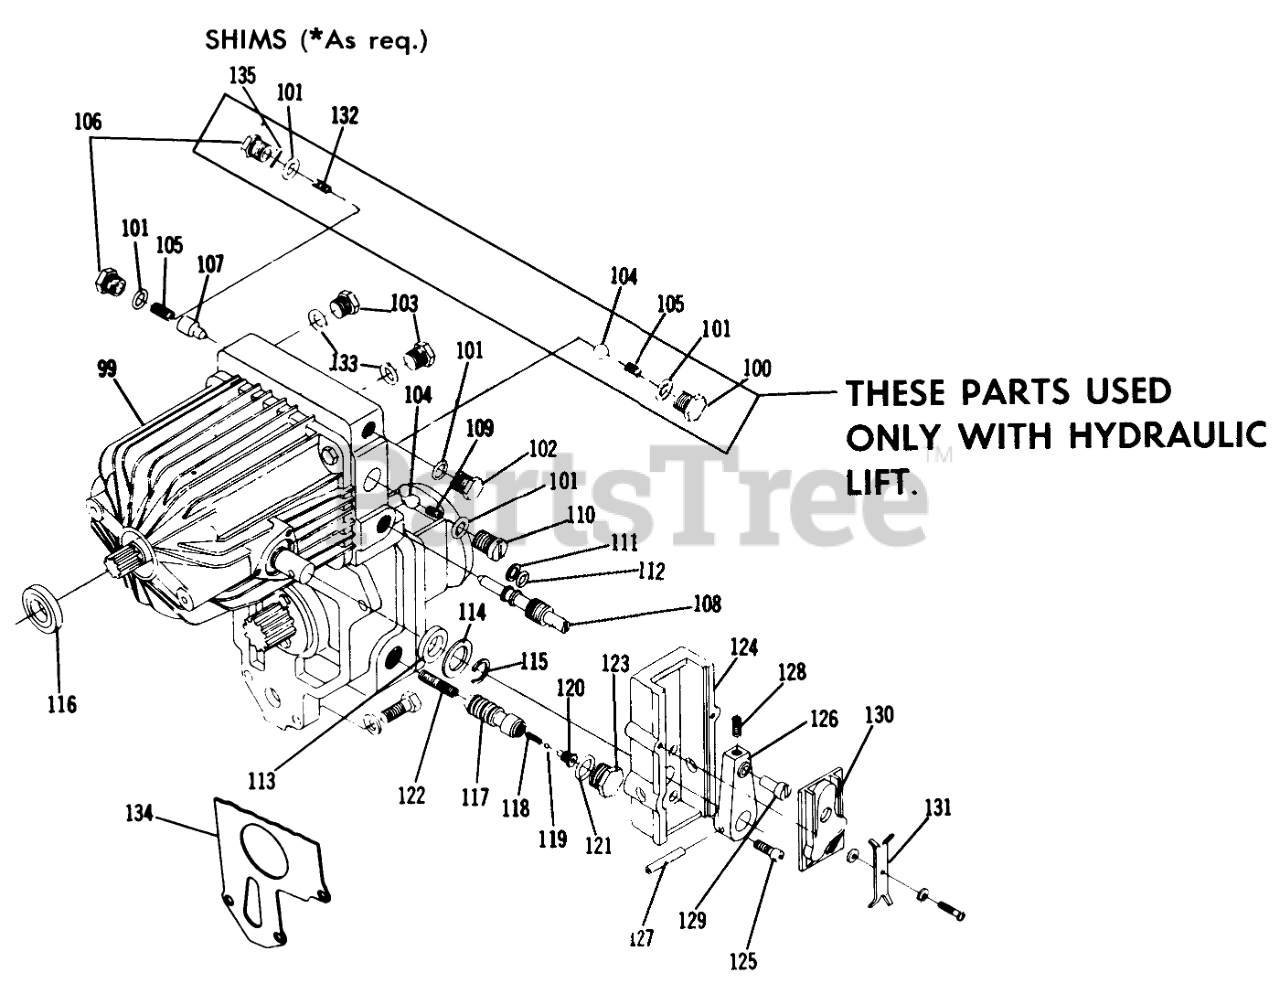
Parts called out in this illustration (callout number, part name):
99	Hydro Unit
100	Plug
101	O RING
103	Plug-Hex 9/16-18
105	Spring Chg. Rel. Valve
107	Cone
108	VALVE
109	Spring
110	PLUG
111	O-RING
112	Back Up Ring
113	SEAL
114	WASHER-LAMBERT
115	RING-LAMBERT
116	SEAL
117	Sleeve
118	SPRING
120	Valve
121	O-Ring
122	Spring
124	SUPPORT CAM BLOCK
125	SHCS 1/4-20 X 1/2
126	Belt Guide
127	PIN-ROLL 1/4 X 1 1/4
129	ECC CAM FOLLOWER
130	CAM
131	TENSION PLATE
131	SCREW
131	LOCKWASHER
131	WASHER
132	SPRING VALVE SUNSTR
133	0-Ring
133	O RING
133	RING BACKUP
134	GASKET
135	Shim Set
